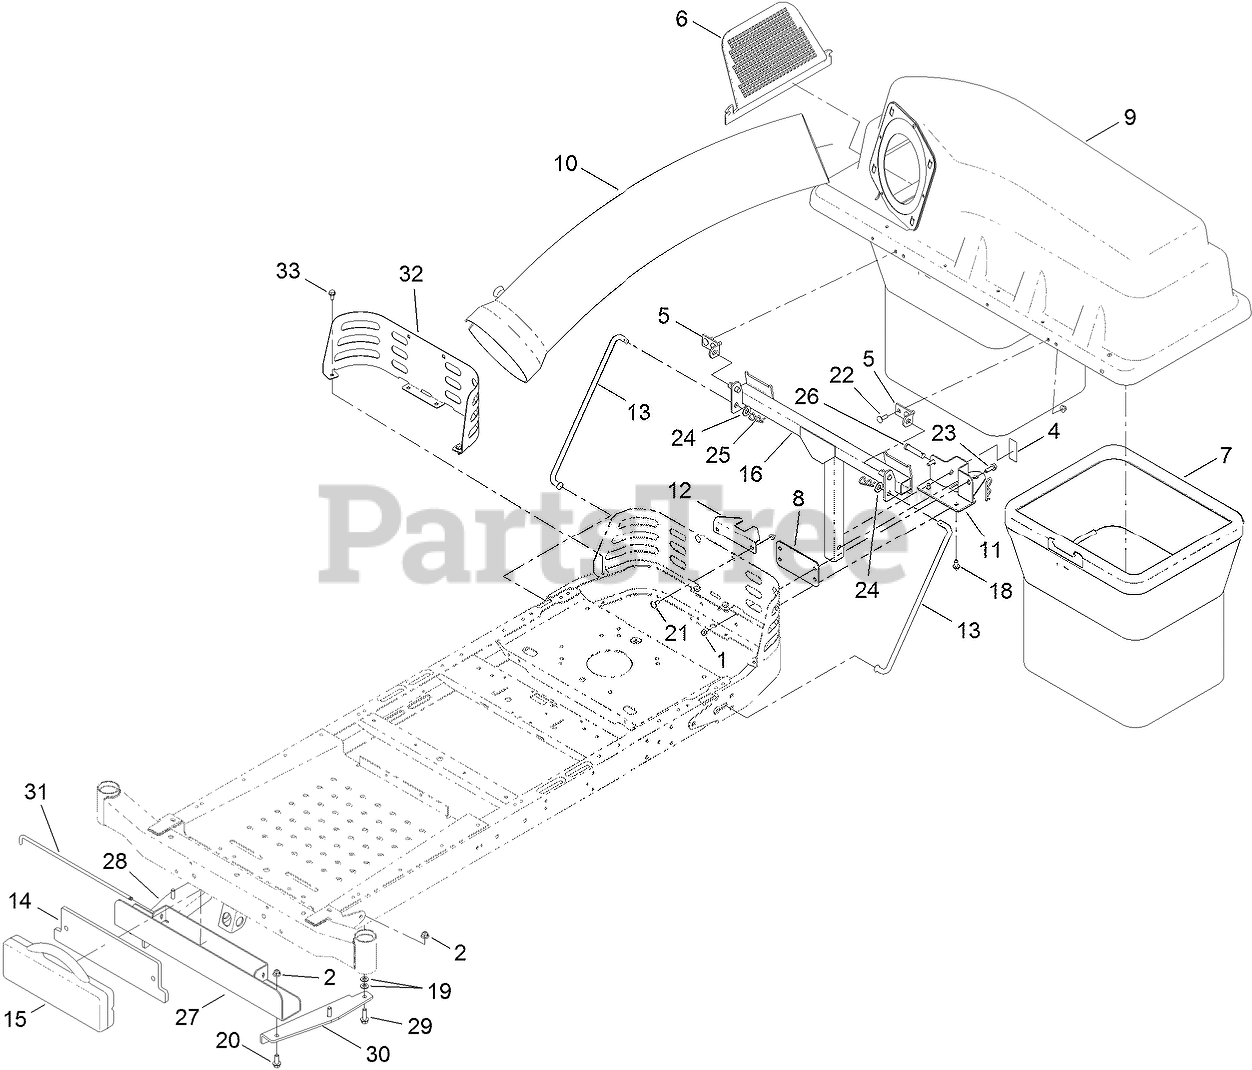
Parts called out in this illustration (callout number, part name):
1	NUT-HF, NI
2	NUT-HF, NI
5	BRACKET-PIVOT, HOPPER
6	SCREEN-BAGGER
7	BAG ASM
9	BAGGER TOP ASM
10	TUBE-BAGGER
11	SUPPORT-BAGGER
12	BRACKET-STABILIZER
13	ROD-SUPPORT
15	WEIGHT-35 POUND
16	FRAME-PIVOT
18	SCREW-HWHTF
19	WASHER-FLAT
20	SCREW-HHF
21	BOLT-CARR
22	BOLT-CARR
23	SCREW-HHF
24	WASHER-FLAT
25	PIN-HAIR
26	PIN-CLEVIS
27	CHANNEL-WEIGHT, BAGGER
28	BRACKET-BAGGER WEIGHT, RH
29	SCREW-HHF
30	BRACKET-BAGGER WEIGHT, LH
31	PIN-WEIGHT
32	GUARD-REAR
33	SCREW-HWHTF
